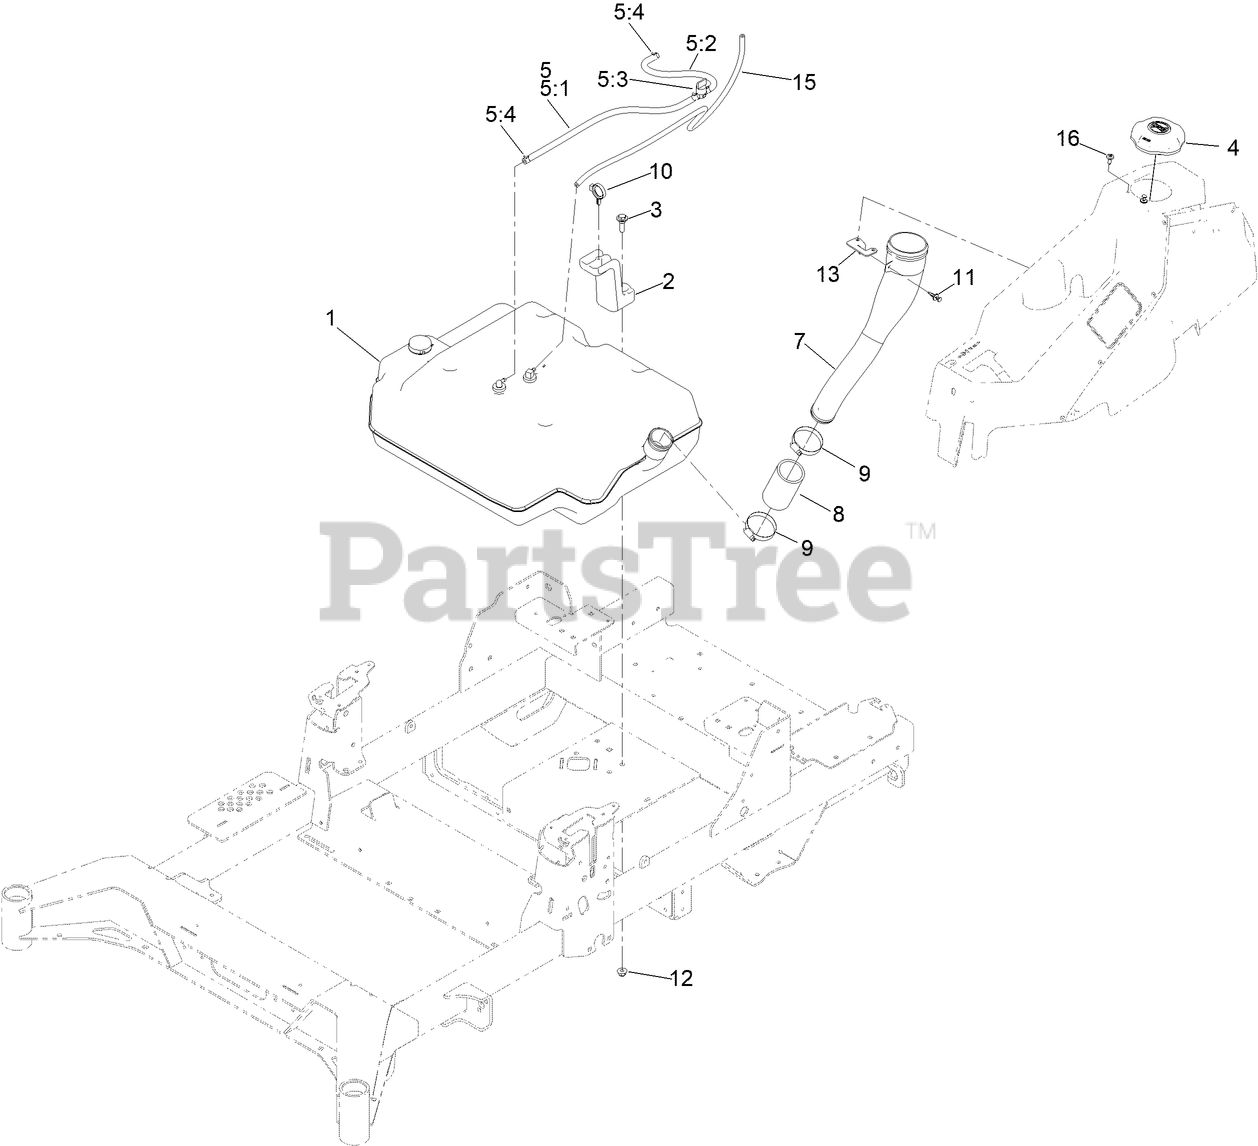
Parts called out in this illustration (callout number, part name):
1	TANK ASM-FUEL
2	RETAINER-TANK, REAR
3	SCREW-SHOULDER, HWH
4	CAP-FUEL, RATCHETING
5	FUEL HOSE ASM
5:1	HOSE-FUEL
5:2	HOSE-FUEL
5:3	VALVE-FUEL
5:4	CLAMP-HOSE
7	NECK-FILLER, FUEL
8	HOSE-FILLER, FUEL
9	CLAMP-HOSE
10	CLAMP-HOSE
11	RIVET-BLIND
12	NUT-HF, NI
13	BRACKET-MOUNTING, FILL
15	HOSE-FUEL
16	SCREW-SHOULDER
